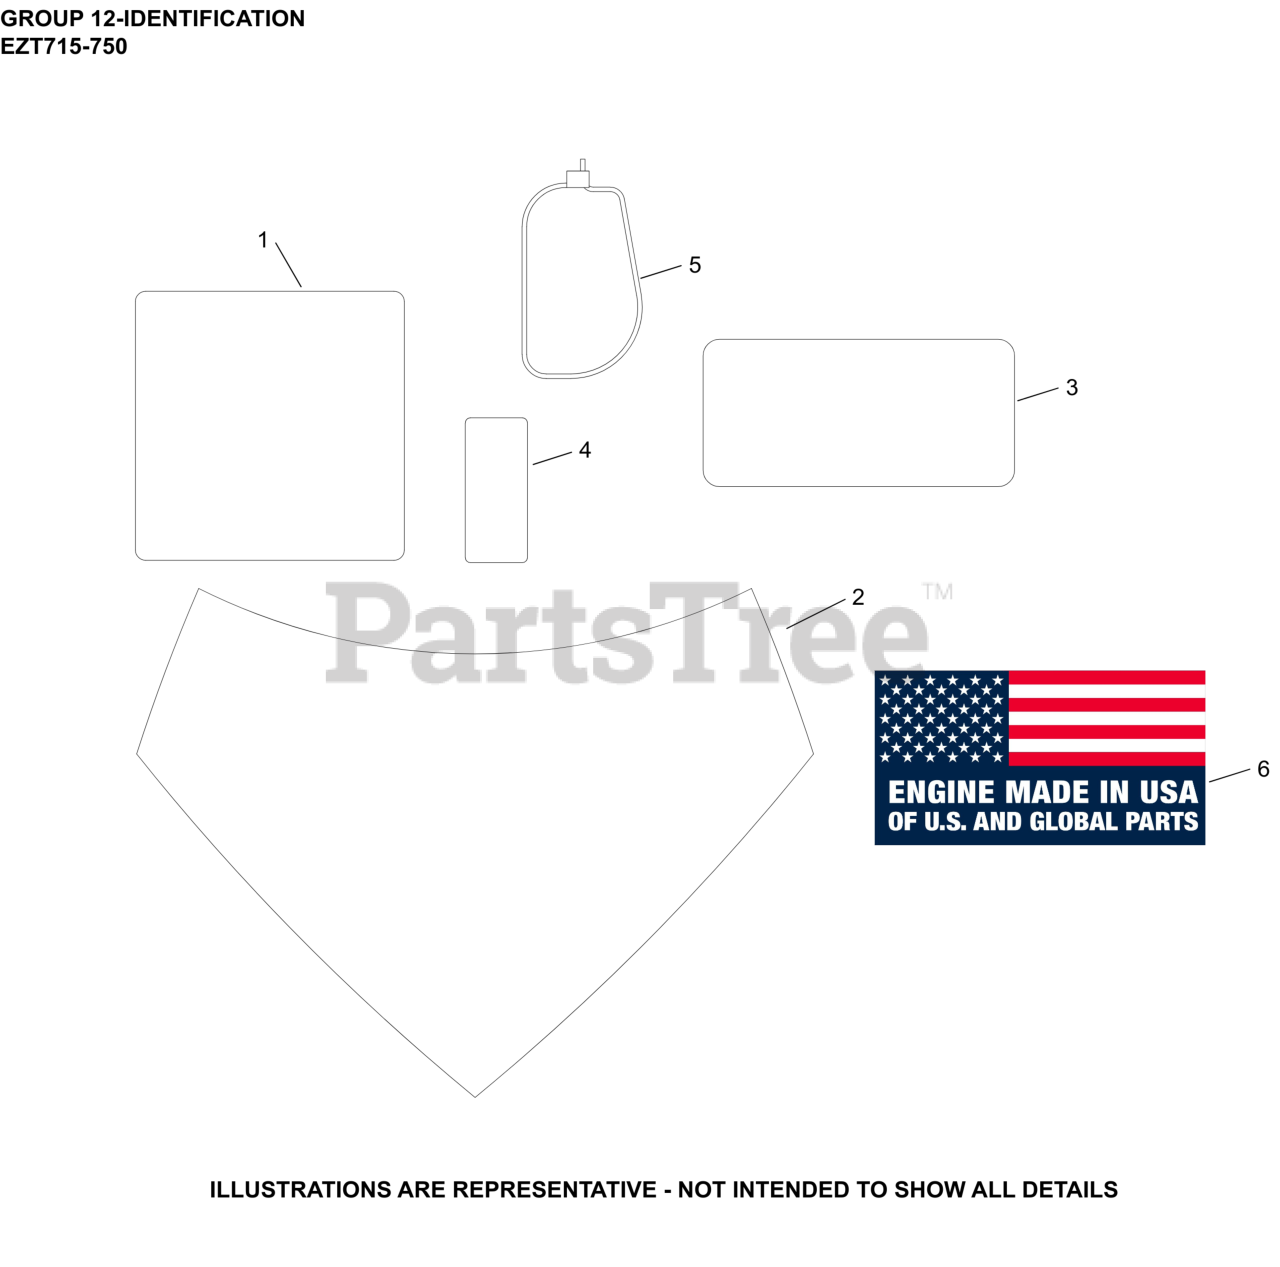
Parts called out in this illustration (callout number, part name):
1	LABEL, CONFIDANT (EZT740, 25HP)
4	LABEL, CLEAR LAMINATION
6	DECAL, USA
NI	DECAL,CONFIDANT HDAC (MAINT.KIT QR CODE)
